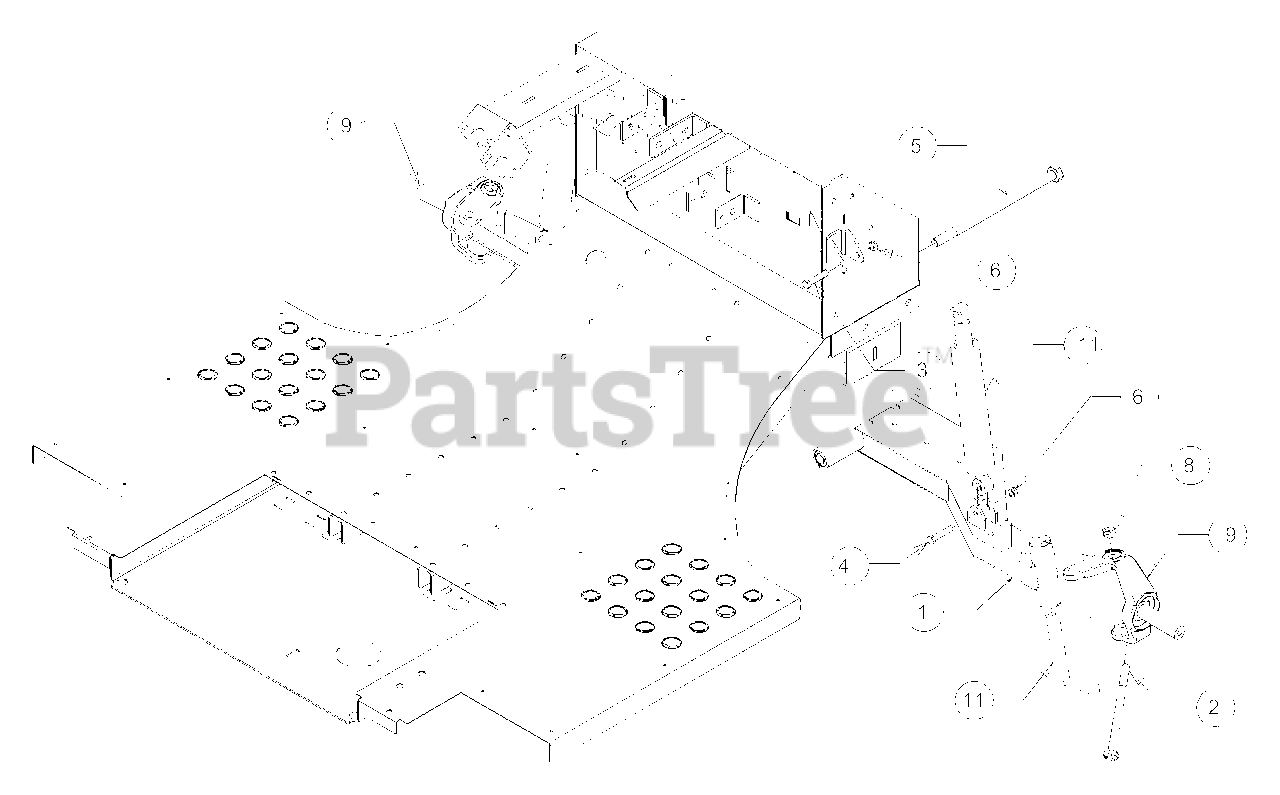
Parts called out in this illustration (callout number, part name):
1	Axle Assembly, Right-front
2	Hex Screw, 1/2-13 x 6.50, Gr5
3	Hex Screw, M10-1.25 x 65mm
4	Hex Screw, M10-1.25 x 50mm
5	Hex Screw, 5/8-11 x 11.13, Gr5
6	Nut, Hex Lock, Nylon, M10 -1.25
8	Nut, Hex Lock, 1/2-13
9	Steering Control Knuckle, RH
11	Tube, .875 x .50 x 4.75
